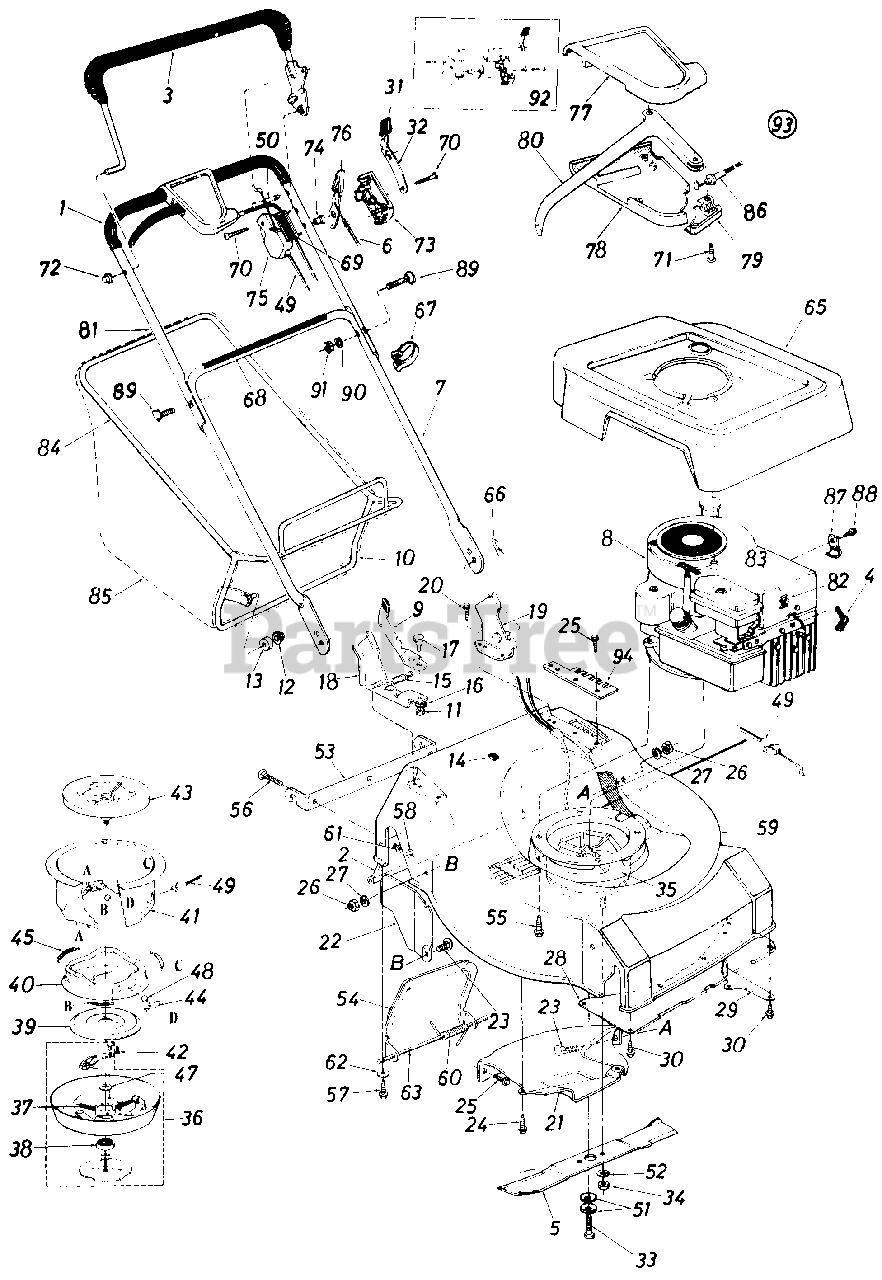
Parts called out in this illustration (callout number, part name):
2	Rear Flap Ass'y.
3	Control Handle - L.H.
4	Spark Plug Insulator
5	22" Blade
6	Throttle Wire - 58.0"
7	Lower Handle
8	Engine
9	Grass Catcher Lock Lever
12	Push Nut 3/8" Rod
13	Plastic Roller
15	Extension Spring
16	L Wash. 5/16" I.D.
17	Shld. Bolt .437" Dia. x .162"
18	Handle Brkt. Ass'y. - R.H.
19	Handle Brkt. Ass'y. - L.H.
20	Hex Hd. Self-Tap Scr. 1/4-20 x 1.00" Lg.
21	Rear Baffle - L.H.
22	Side Baffle
23	Carriage Bolt 1/4-20 x .50" Lg.
24	Hex Wash. Hd. AB-Tap Scr. 1/4 x .62" Lg.
25	Hex Wash. Hd. Drill Scr. 1/4 x .75" Lg.
26	Hex Nut 1/4-20 Thd.
27	L-Wash. 1/4" I.D.
28	Front Cover Plate
29	Left Strap
30	Hex Wash. Hd. AB-Tap Scr. 1/4 x .62" Lg.
31	Spring Lever Knob
32	Lockout Spring
33	Hex Bolt 3/8-24 x 2.00" Lg. (Grade 8)
34	Hex Nut 3/8-24 Thd. (Grade 8)
35	Blade Brake Clutch Ass'y. Comp.
36	Clutch Blade Housing Ass'y.
37	Compression Spring .35" O.D. x 2.00" Lg.
38	Ball Brg. .669" I.D. x 1.574" O.D. x .47
39	Clutching Cone
40	Brake Cup Cone
41	Clutch Housing
42	Hex TT-Tap L-Scr. 1/4-20 x .75" Lg.
43	Fan Adapter
44	Ball Block
45	Extension Spring .35" O.D. x 1.75" Lg.
47	Fl-Wash. .690" I.D. x 1.060 O.D. x .030
48	Steel Ball .500" Dia.
49	Clutch Cable - 46.0"
50	Lock Pin .314" Dia. x 1.70
51	Bell-Wash. .400" I.D. x .88" O.D.
52	L-Wash. 3/8" I.D.
53	Grass Catcher Hitch Brkt.
54	Chute Door
55	Hex Wash. Hd. TT-Tap Scr. 3/8-16 x 1.00" Lg.
56	Carriage Bolt 1/4-20 x .75" Lg.
57	Hex Washer. Hd. "AB"-Tap Scr. 1/4 x .62"
58	Sems Nut 1/4-20 Thd.
59	22" Deck Ass'y.
60	Torsion Spring .34" I.D. x 2.38" Lg.
61	Fl-Wash. .281" I.D. x .73" O.D. x .063
62	Fl-Wash. .285" I.D. x 1.25" O.D. x .060
63	Rod .25" Dia. x 8.25" Lg.
65	Shroud Ass'y,
66	Intern. Cot. Pin 5/16" Dia.
67	Cable Tie
68	Instruction Label - Handle
69	Control Label - Throttle
70	Truss Mach. B-Tap Scr. #12 x 1.50" Lg.
71	Flat C-Sunk AB-Tap Scr. #10 x .75" Lg.
72	Cap Speed Nut 5/16" Rod
73	Control Panel Half
74	Control Disc Pin
75	Clutch Panel Half
76	Throttle Control Lever
77	Control Cover Half - Upper
78	Control Cover Half - Lower
79	Cable Mtg. Cap
80	Control Lever
81	Upper Handle
82	Hex AB-Tap Scr. #8 x .38
83	Casing Clamp
84	Grass Catcher Upper Frame
85	Grass Bag
86	Self-Propelled Clutch Cable - 50.0" Lg.
87	Casing Clamp
88	Hex B-Tap Scr. #10 x .38" Lg.
89	Curved Carriage Bolt 5/16-18 x 1.38" Lg.
90	L-Wash. 5/16" I.D.
91	Hex Nut 5/16-18 Thd.
92	Kit - Control Housing Comp.
93	Kit - Clutch Housing Comp.
94	Reinforcing Brkt.
